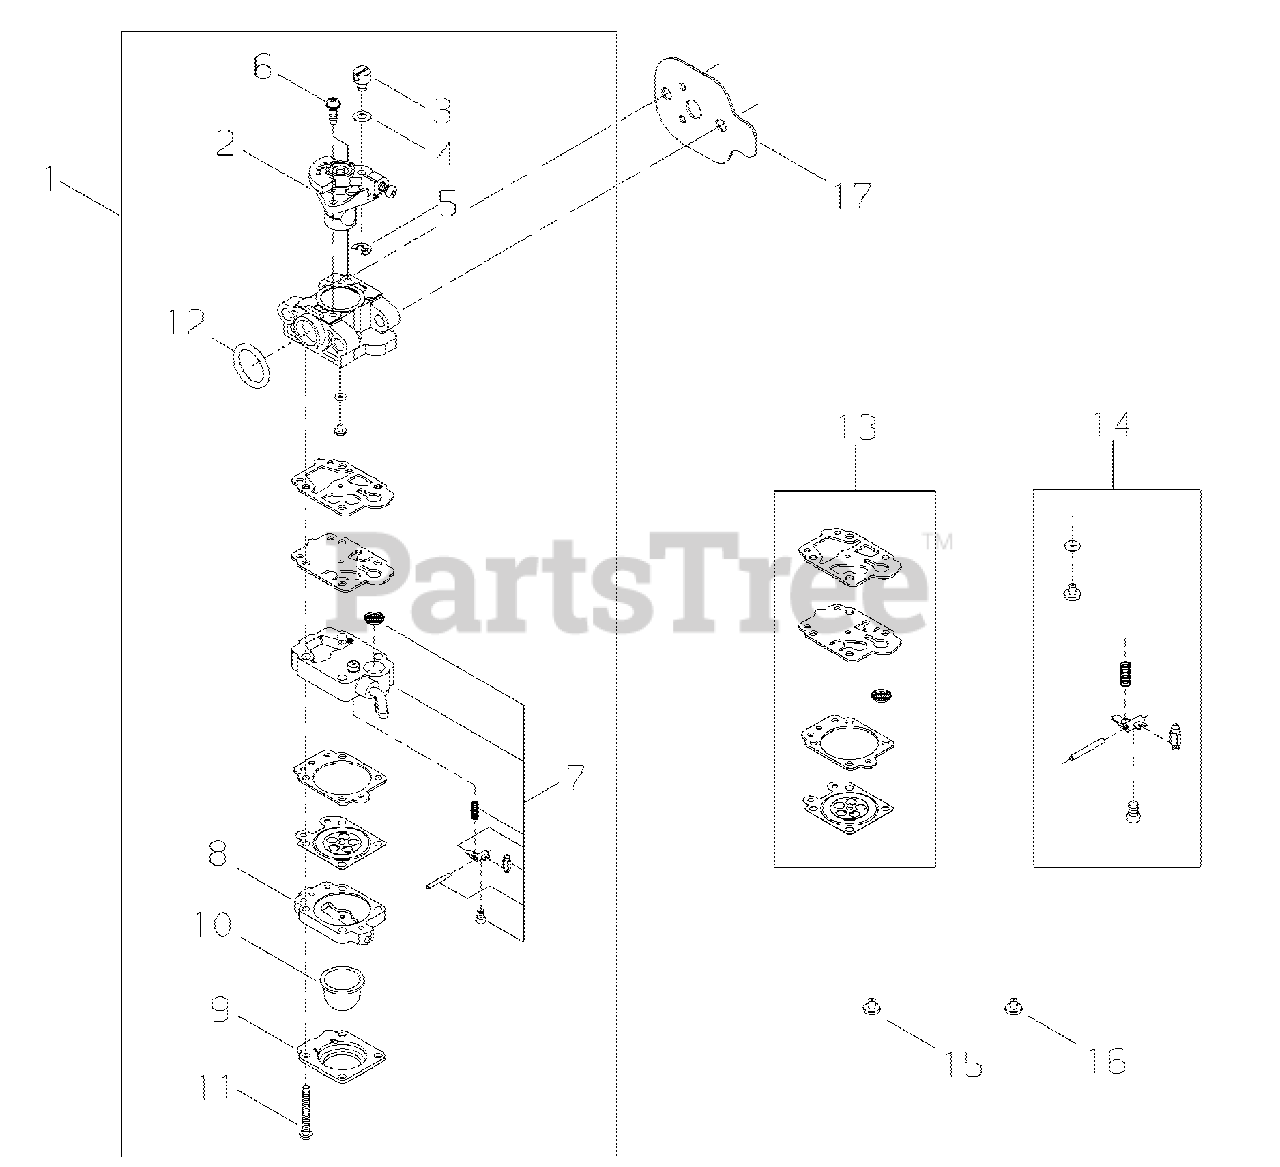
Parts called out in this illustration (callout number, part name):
1	CARBURETOR
2	VALVE ASSY, THROTTLE
3	SWIVEL
4	WASHER
5	E-RING
6	SCREW, THROTTLE COLLAR
7	BODY ASSY, PUMP
8	BODY ASSY, PURGE
9	RETAINER, PURGE BULB
10	BULB, PURGE
11	SCREW
12	O-RING 15
13	GASKET / DIAPHRAGM KIT
14	VALVE KIT, INLET NEEDLE
15	JET, MAIN #40
16	JET, MAIN #39
17	GASKET, INTAKE
